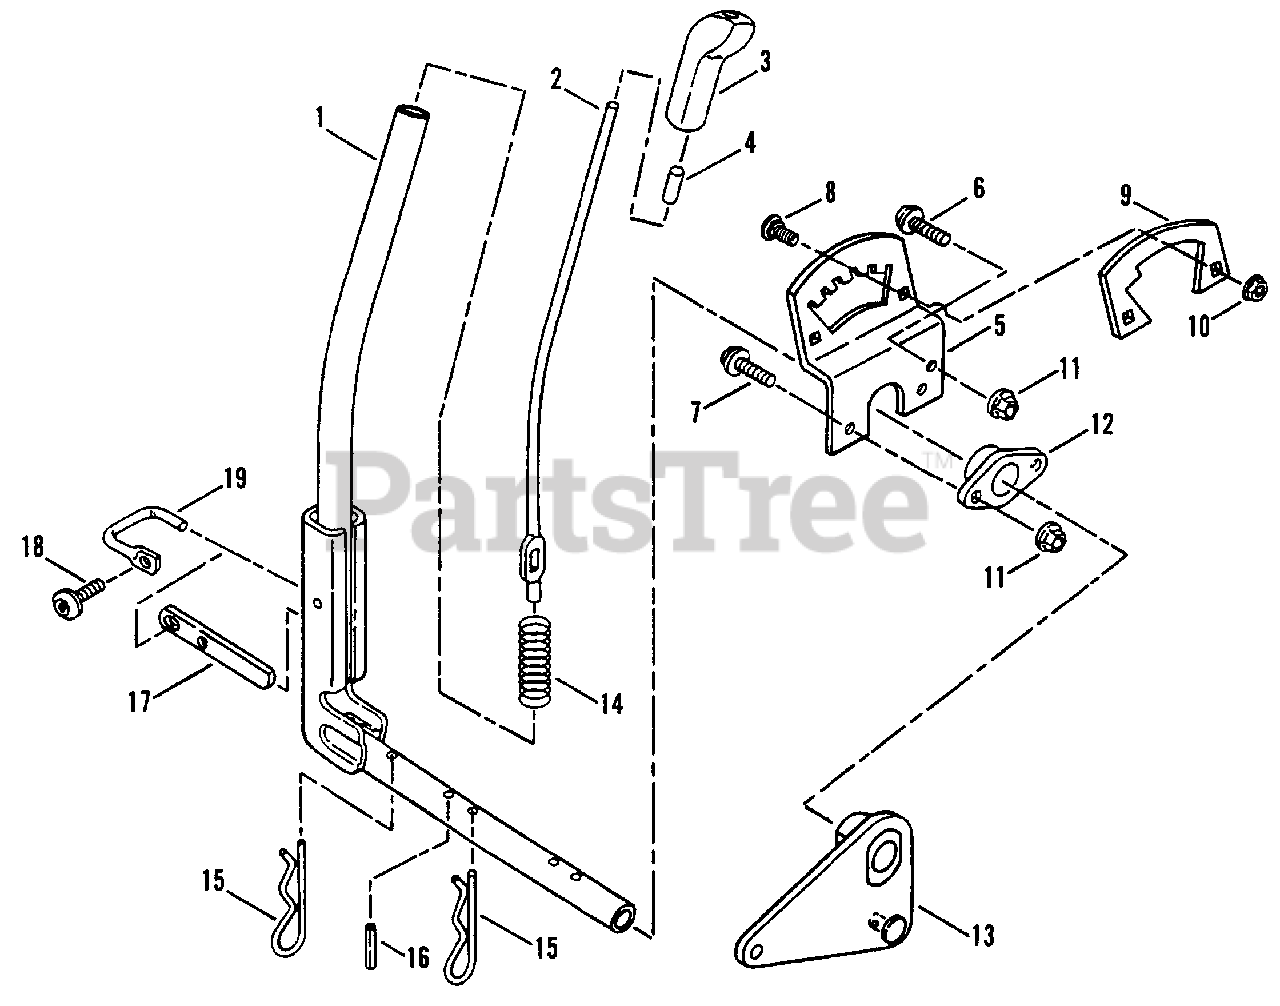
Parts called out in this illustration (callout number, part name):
1	LEVER, Implement Lift
2	ROD, Lift Lever
3	KNOB, Lift Lever
4	CAP, Lift Lever Rod
5	QUADRANT, Lift Lever
6	SCREW, 5/16-18 x 5/8" Truss Head (Torx)
7	SCREW, 5/16-18 x 7/8" Truss Head (Torx)
8	BOLT, 1/4-20 x 1/2" Short Neck Carriage
9	DETENT, Highcut Lockout
10	NUT, 1/4-20 Hex Flange Lock
11	NUT, 5/16-18 Hex Flange Lock
12	PIVOT, Lift Lever
13	BELLCRANK, Lift Lever
15	PIN, Hair, 5/32 x 2 5/8"
16	PIN, Dowel, 1/4 x 1 1/8"
17	DETENT, Latch
18	SCREW, 1/4-20 x 5/8" Truss Head (Torx)
19	LATCH, Pivot
